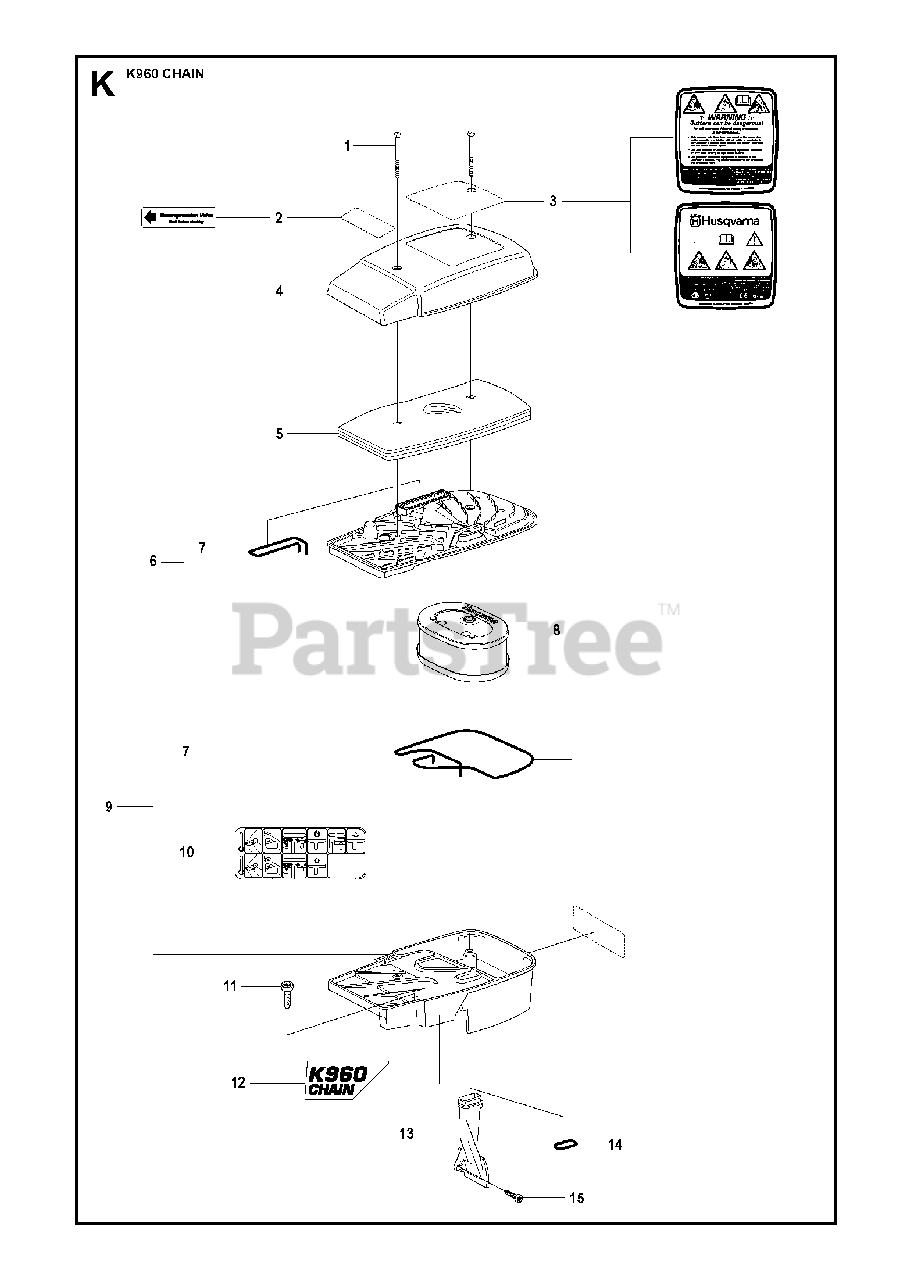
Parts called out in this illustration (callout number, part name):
1	SCREW ITXSCM
3	LABEL
4	COVER
6	FILTER BOTTOM
9	CYLINDER COVER ASSY
11	SCREW ITXSCM
15	SCREW ITXSCM
